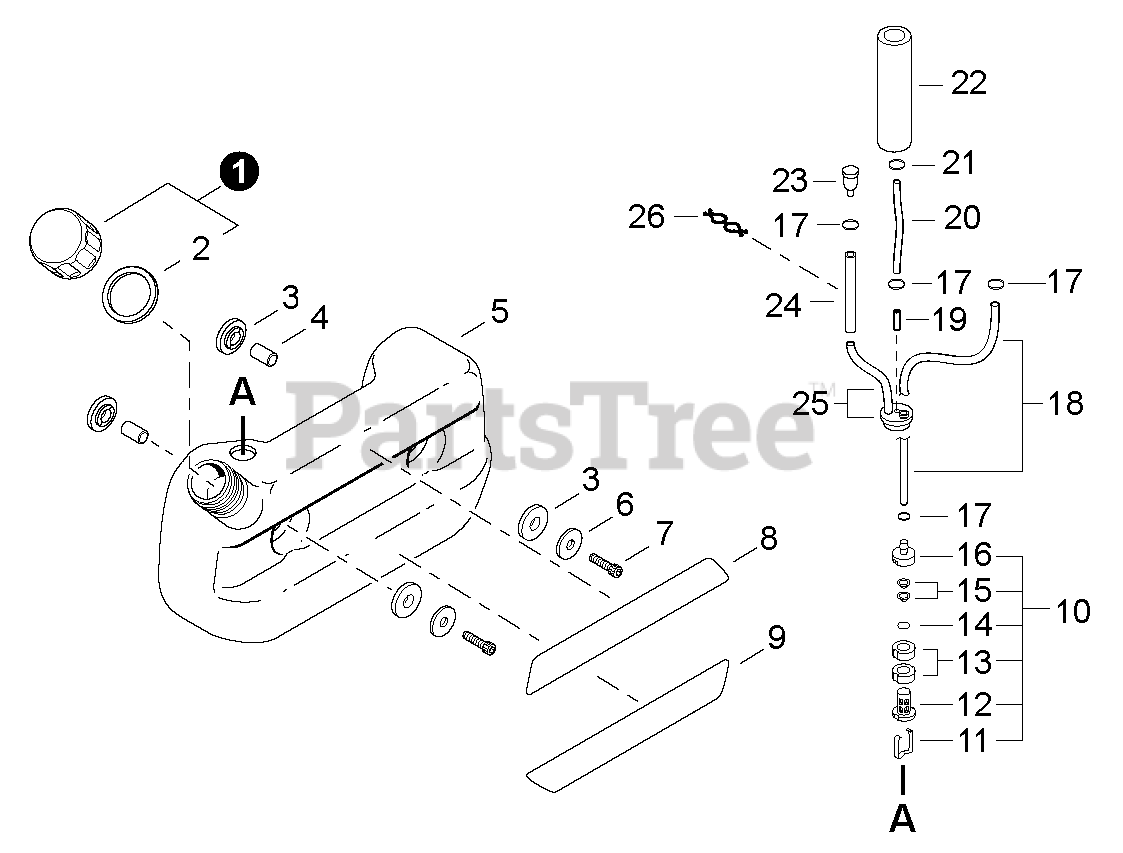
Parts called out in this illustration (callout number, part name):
1	CAP ASSY, FUEL
2	GASKET, FUEL CAP
3	CUSHION
4	COLLAR Ø6×L15
5	TANK, FUEL
6	COLLAR Ø23ר6.5×L3.2
7	BOLT M6×25
8	LABEL, MODEL
9	LABEL, SHINDAIWA
10	FILTER, FUEL
11	FILTER, FUEL
12	FILTER, FUEL
13	FILTER, FUEL
14	RING, RETAINING
15	FILTER, FUEL
16	FILTER, FUEL
17	CLIP Ø6
18	PIPE, FUEL
19	CONNECTOR, PIPE
20	PIPE, FUEL RETURN
21	CLIP
22	TUBE, INSULATOR
23	VENT ASSY
24	TUBE, INSULATOR
25	GROMMET, FUEL W/VENT PIPE
26	CLIP
